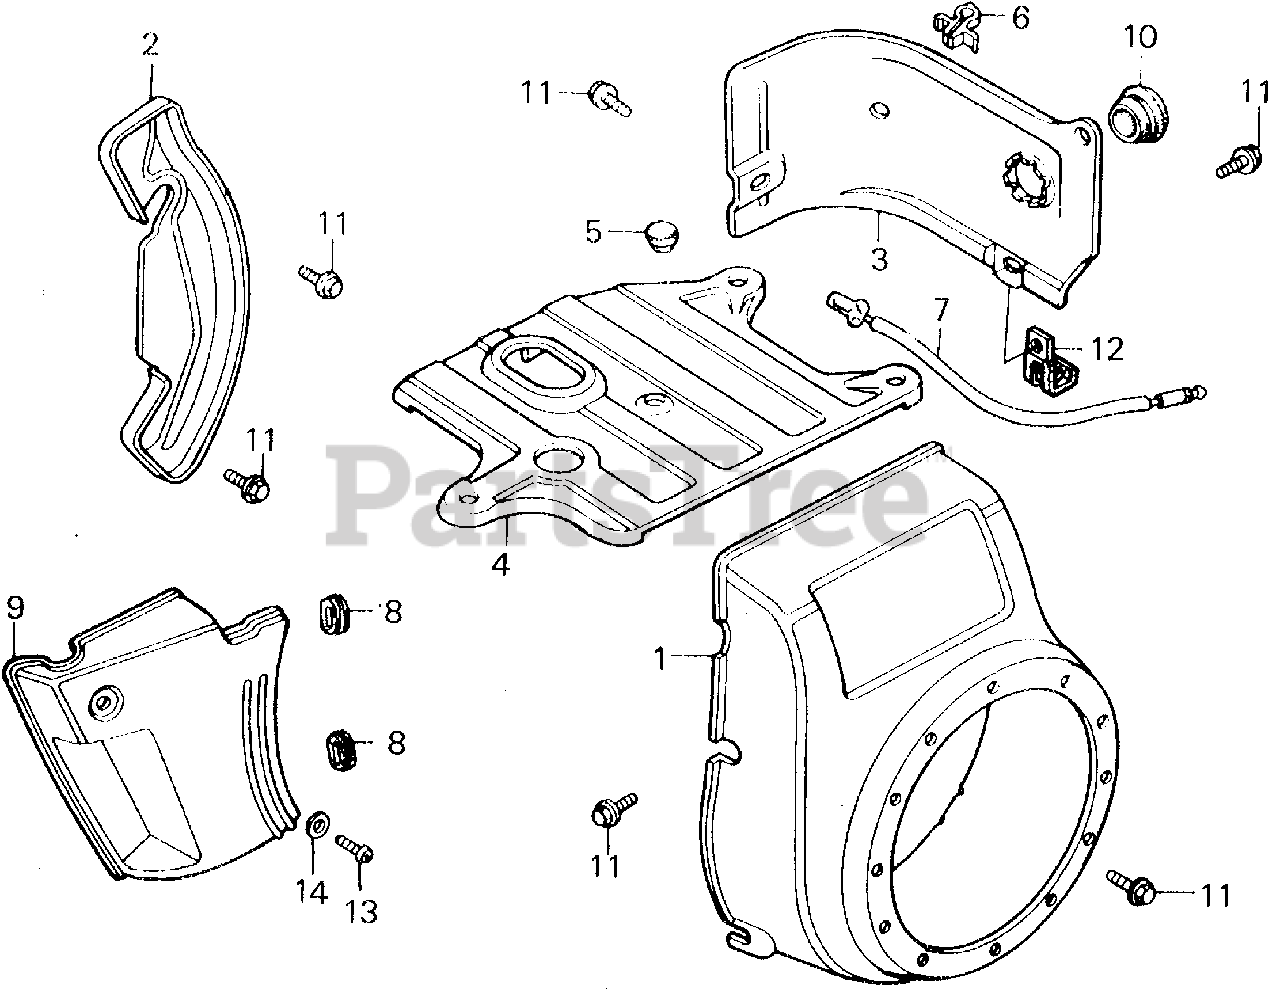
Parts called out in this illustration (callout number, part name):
1	COVER, FAN *R8* (BRIGHT RED)
2	PLATE, SIDE
3	SHROUD *R8* (BRIGHT RED)
4	COVER, TOP *R8* (BRIGHT RED)
5	GROMMET, TOP COVER
6	CLIP, IGNITION WIRE
7	WIRE A, ENGINE STOP
8	RUBBER, CHAIN CASE SETTING
9	COVER, ENGINE SIDE
10	GROMMET, DRAIN HOLE
11	BOLT, FLANGE (6X12) (CT200)
12	CLIP, CABLE
13	SCREW, PAN (6X12)
14	WASHER, PLAIN (6MM)
